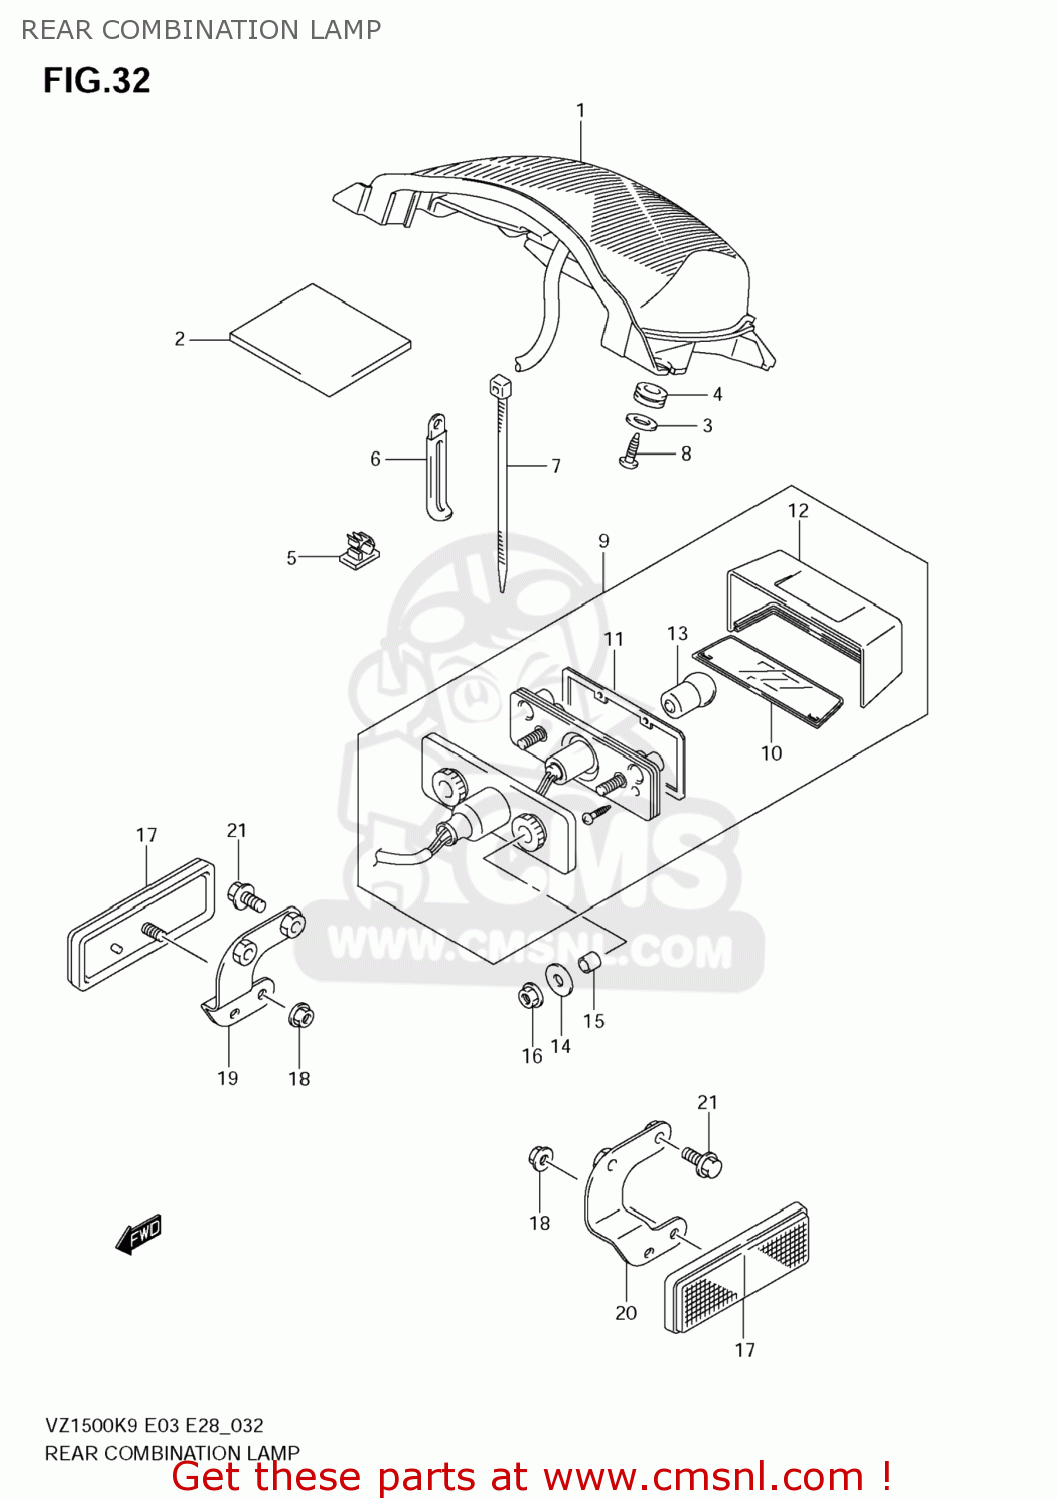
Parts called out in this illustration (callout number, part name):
1	LAMP ASSY,RR COMBINATION
2	CUSHION,HELMET BOX
3	WASHER(5.5X20X1.2)
4	CUSHION
5	CLAMP
6	CLAMP(L:45)
7	CLAMP(L:145)
8	SCREW
9	LAMP ASSY,LICE
10	LENS LICENCE
11	GASKET (NAS)
12	COVER,LICENSE LAMP
13	BULB(12V5W,BF150-40160A)
14	WASHER(6.5X20X1.2)
15	SPACER(6.5X9X8)
16	NUT
17	REFLECTOR ASSY,RR
18	NUT
19	BRACKET,RR SIDE RR,R
20	BRACKET,RR SIDE RR,L
21	SCREW
